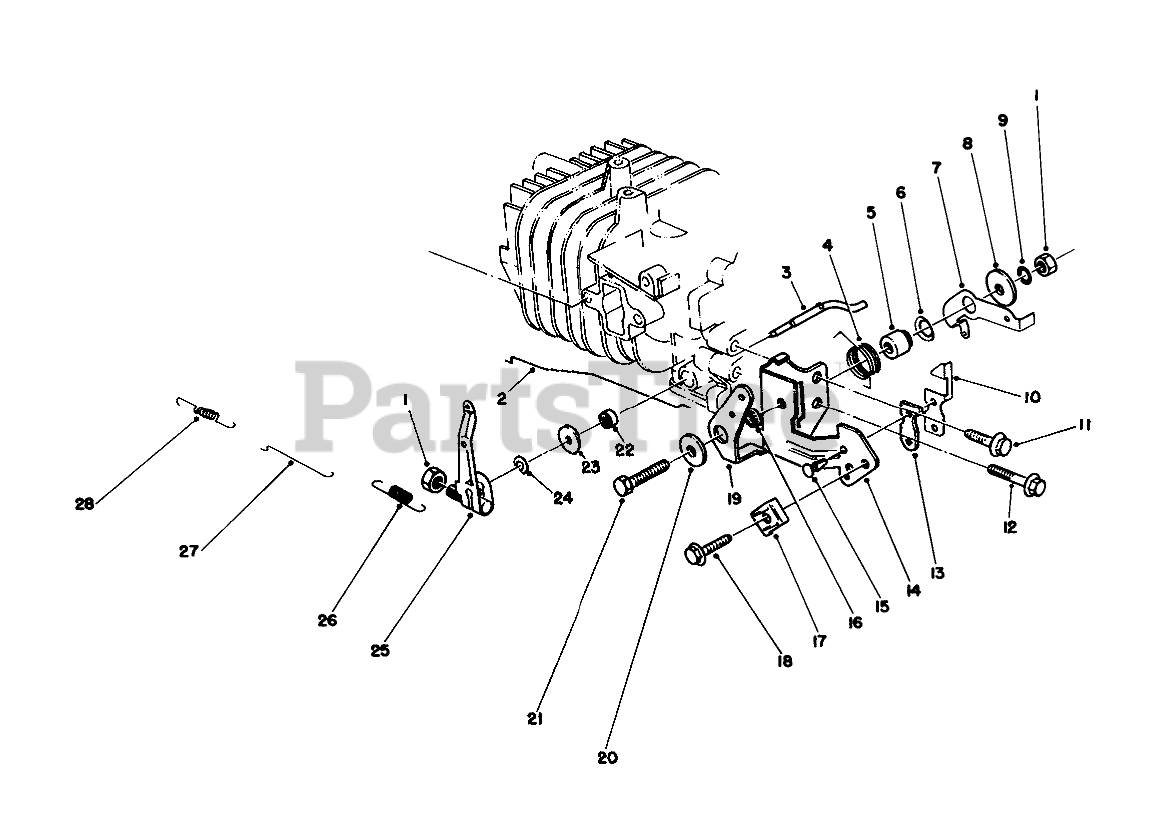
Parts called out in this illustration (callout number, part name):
2	CHOKE ROD
3	Shaft-Govemor
4	SPRING-CHOKE LEVER
5	Gov Lever Spacer
6	Washer-Gov. Spring Lever
7	LEVER-SPRING, GOVERNOR
8	WASHER
9	LOCKWASHER
10	TERMINAL-KILL SWITCH
13	INSULATOR-KILL SWITCH
14	BRACKET-THROTTLE, CONTROL
15	KILL SWITCH RIVET
16	SPACER-CHOKE LEVER
17	CLAMP
19	LEVER-CONTROL, CHOKE
20	WASHER
22	SEAL-OIL
23	WASHER
24	E-RING
25	GOVERNOR ARM
26	SPRING-GOVERNOR
27	ROD-CARBURETOR
28	SPRING
